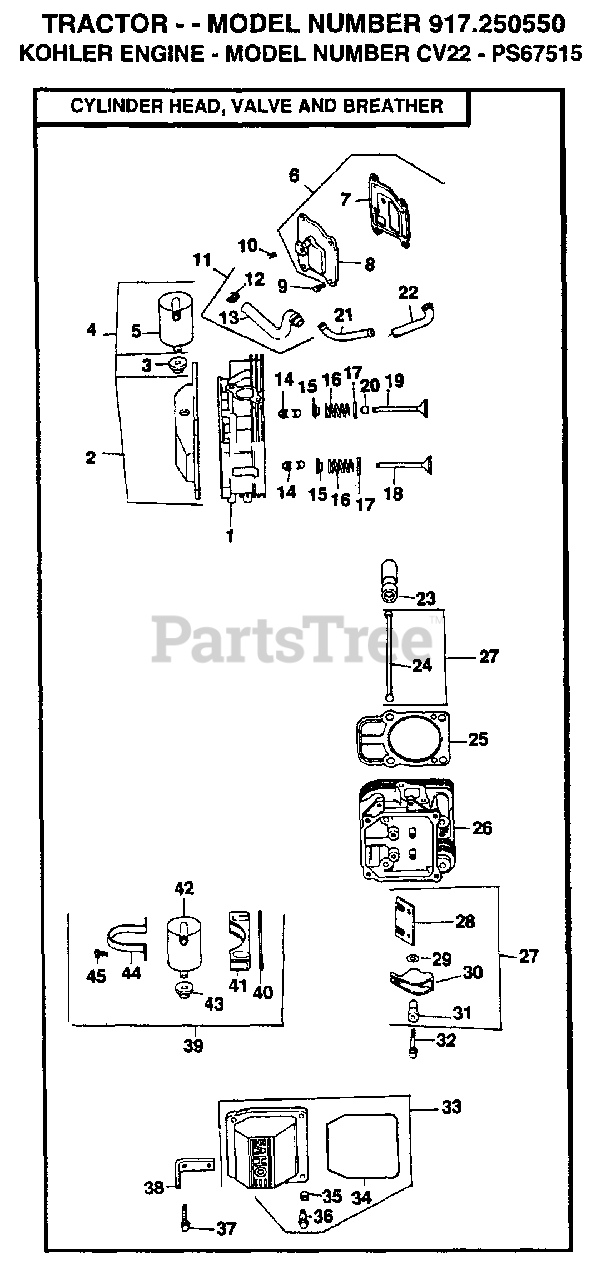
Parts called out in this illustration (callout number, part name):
1	HEAD ASSEMBLY
2	COVER, ROCKER
3	KIT, BREATHER
4	GROMMET, RUBBER
5	COVER, BREATHER
7	SCREW, FUEL PUMP
9	KIT, RETAINER
10	CAP, VALVE SPRING
11	SPRING, VALVE
13	VALVE, EXHAUST, STANDARD SIZE
14	VALVE, INTAKE, STANDARD SIZE
15	SEAL, VALVE STEM
18	LIFTER, VALVE
20	GASKET, CYLINDER HEAD
21	HEAD ASSEMBLY
24	SCREW, ROCKER ARM
25	No Desciption for Part
